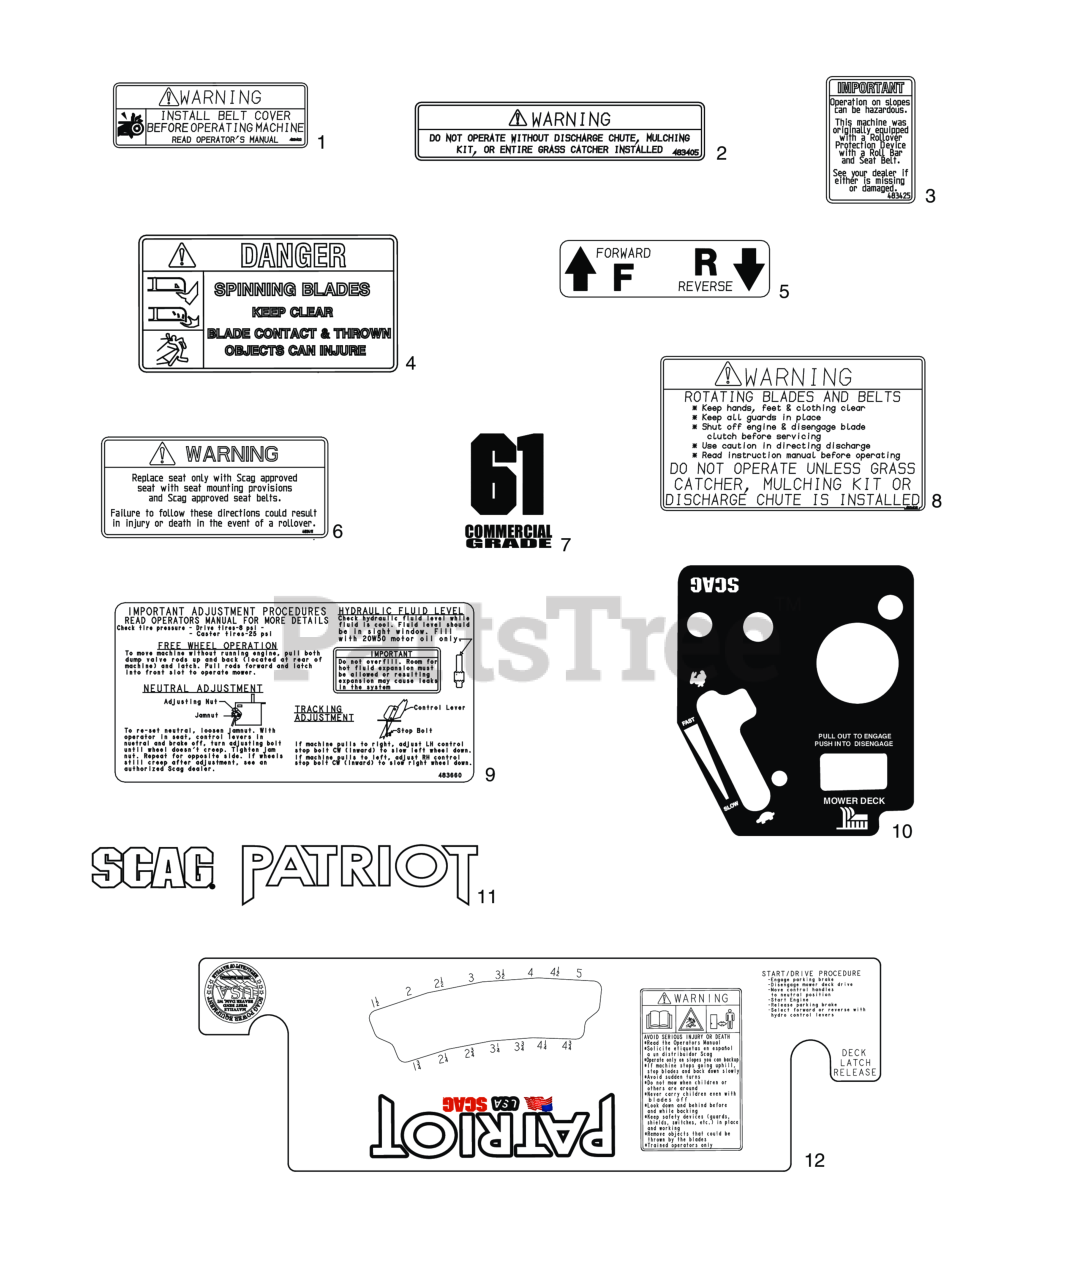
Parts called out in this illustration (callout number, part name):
1	Decal, Warning - Belt Cover
2	Decal, Warning-Discharge
3	Decal, ROPS
4	Decal, Spinning Blades
5	Decal, Traction Control
6	Decal, Seat Replacement
7	Decal, 61 Commercial
8	Decal, Warning - Rotating Blades
9	Decal, Adjustment SFZ
10	Decal, Instrument Panel
11	Decal, Front SPZ, (Scag Gold Logo)
12	Decal, Cutting Height, (Scag Gold Logo)
